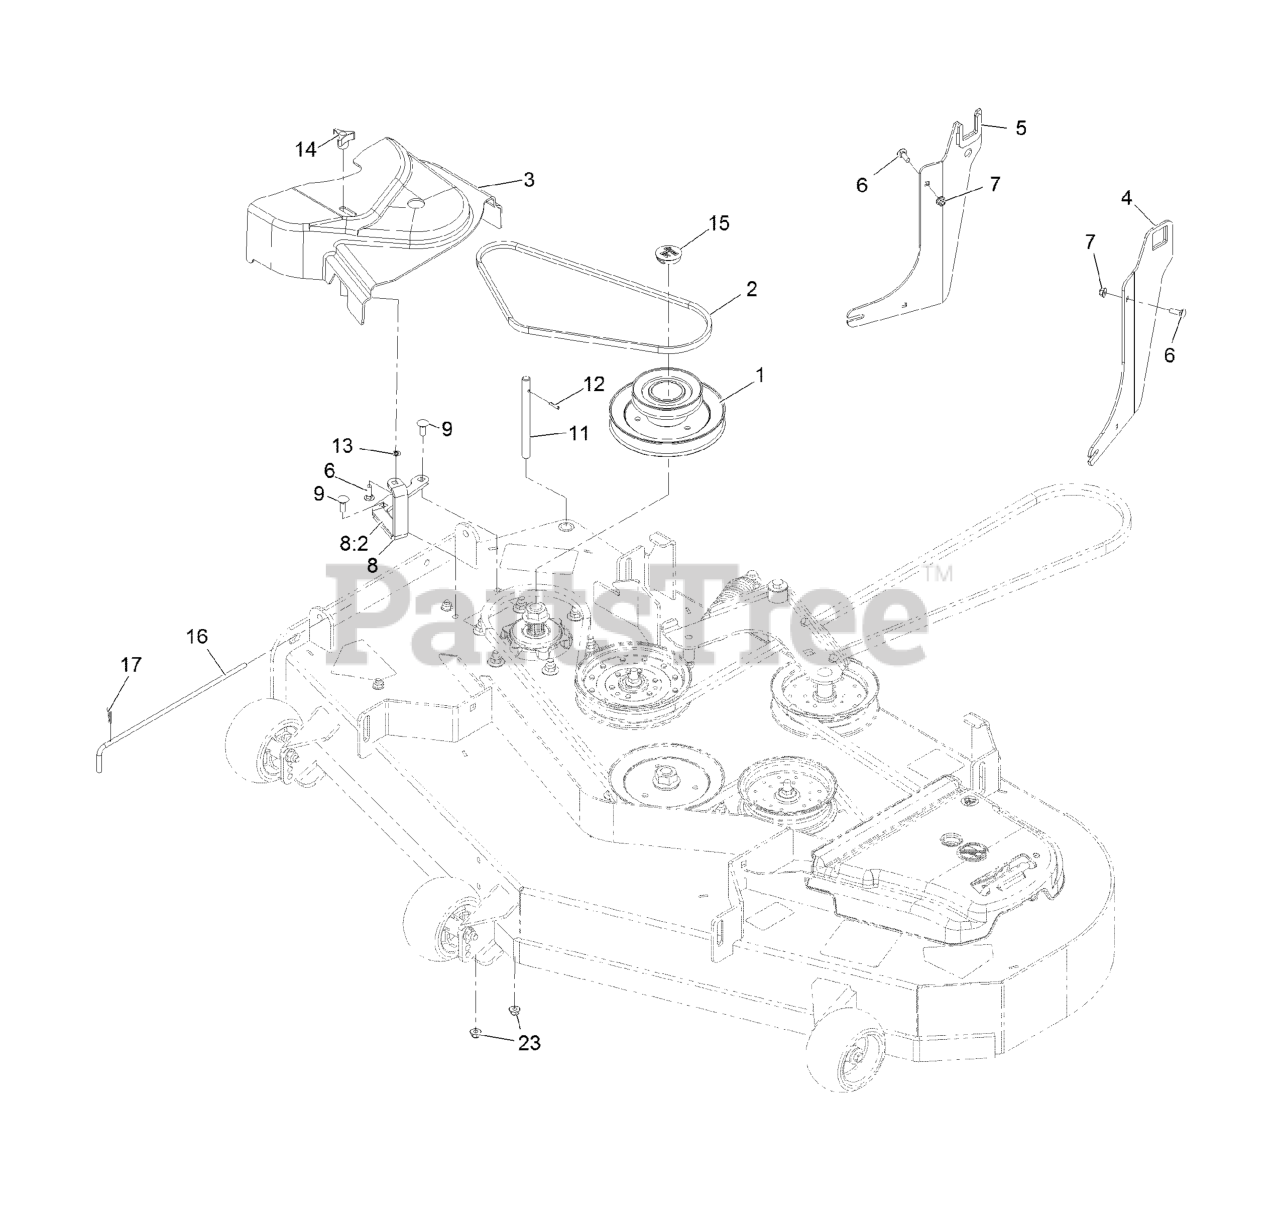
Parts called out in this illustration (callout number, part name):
1	JACKSHAFT,UV DRIVE 524 SP
2	BELT-BLOWER
3	COVER-BELT, UV 52
4	BRACKET ASM, LH
5	BRACKET ASM, RH
6	BOLT-CARR
7	NUT-HF, NI
8	ASM-CVR BRKT W/DECAL
8:2	DECAL-DANGER
9	BOLT-CARR
11	SHAFT-CATCHER, GRASS
12	PIN-ROLL
13	RING-RETAINING, BOLT
14	KNOB-3 PRONG
15	PLUG, BLACK NYLON 1.75
16	PIN,CHUTE PIVOT
17	PIN-COTTER
23	Nut-Nyloc 3/8-16 Flg
